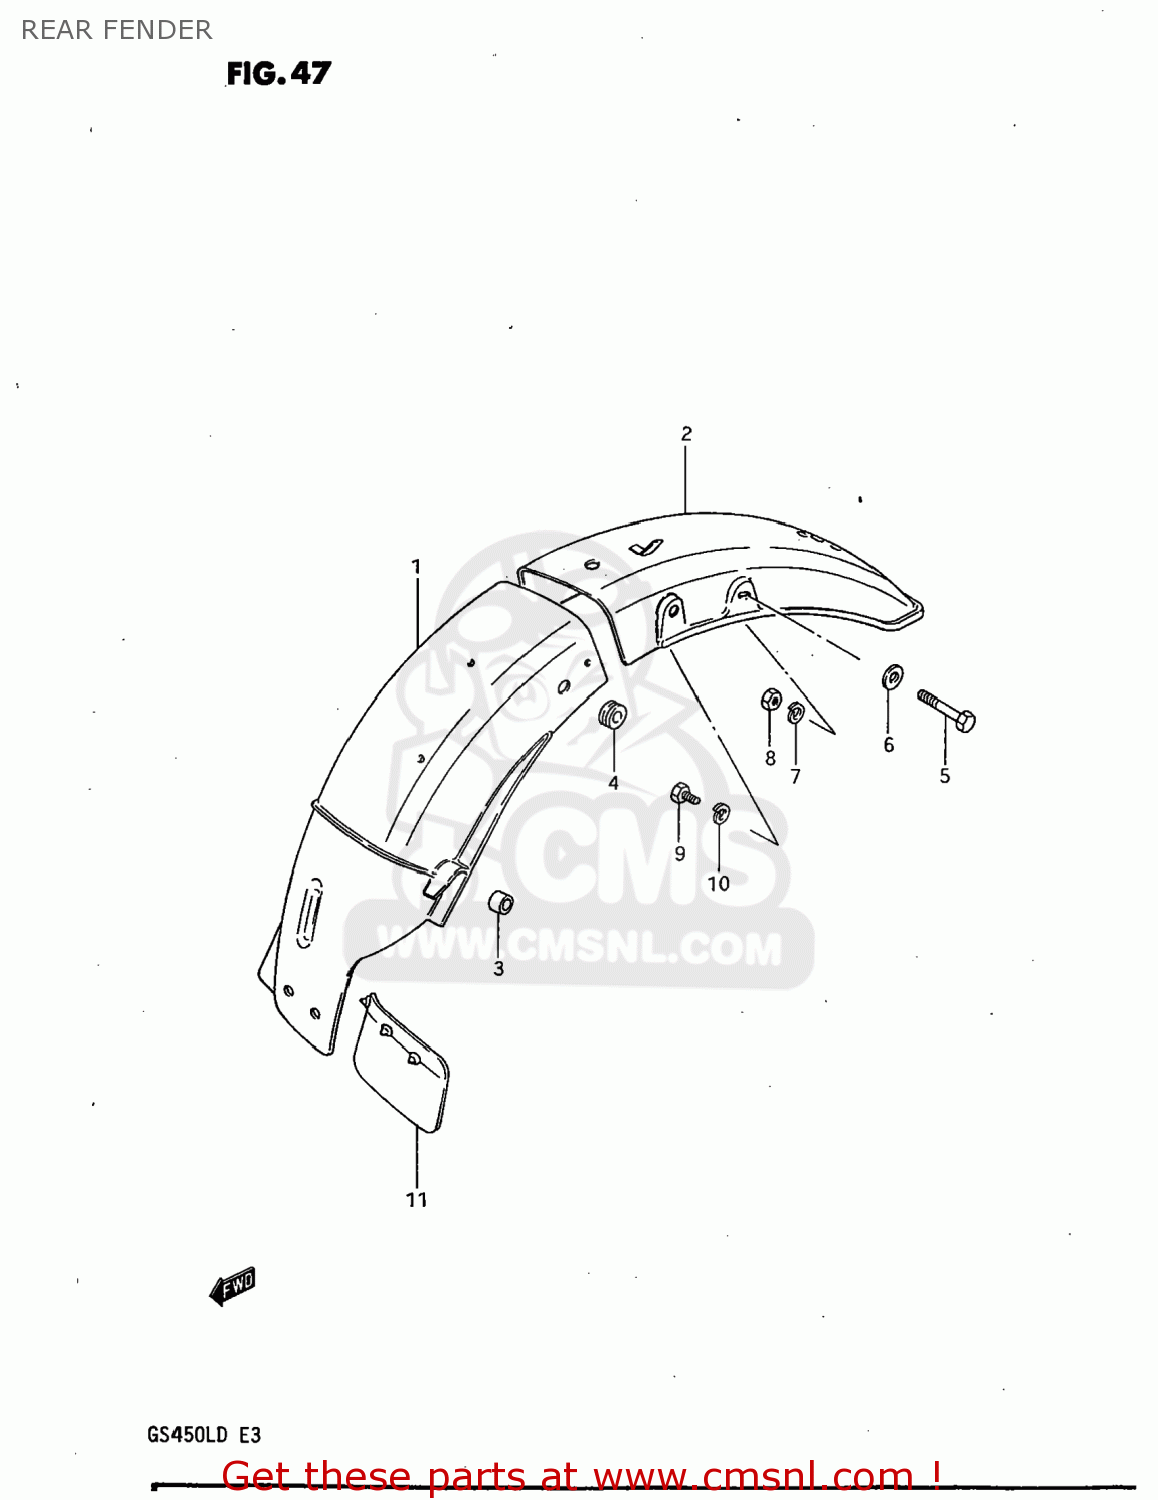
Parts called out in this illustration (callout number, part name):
1	FENDER,REAR
2	FENDER,REAR
3	CUSHION
4	CUSHION
5	BOLT
6	WASHER
7	LOCK WASHER
8	NUT
9	BOLT
10	LOCK WASHER
11	GUIDE,RR FENDER MUD
